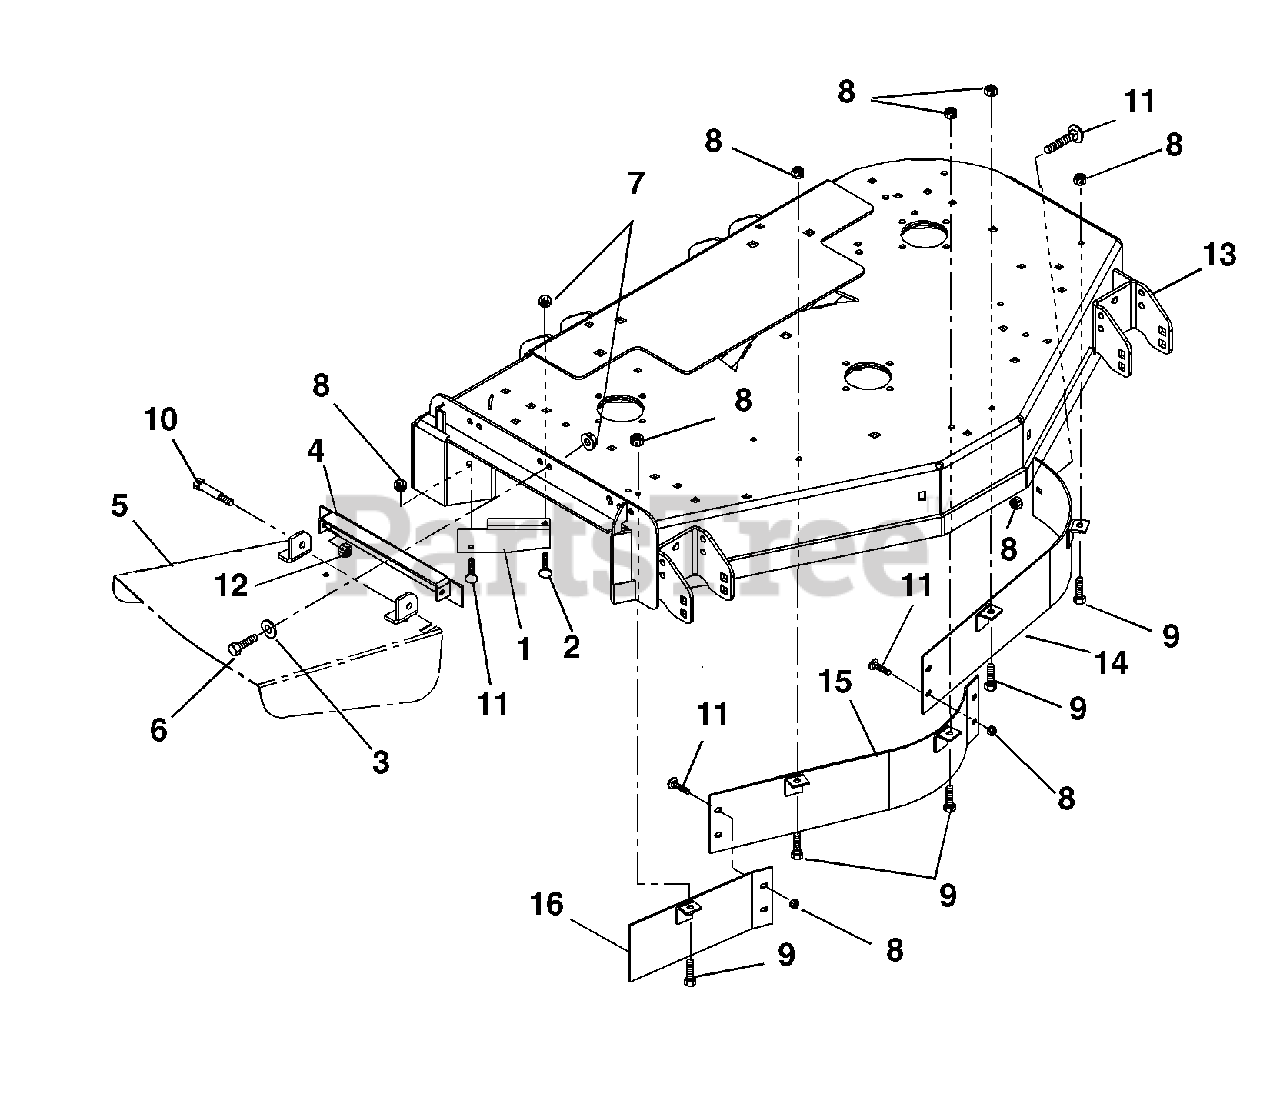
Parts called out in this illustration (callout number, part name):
1	DEFLECTOR - 52"/34"
1	DEFLECTOR, 60" (BLACK)
2	@BLT-RDHDSQNK .38-16X1.00 G5YZ
3	@WSHR-FL-STL.38X.875X.083 YWZC
4	WMT, DISCH CHUTE BRKT - ORANGE
4	WMT, CHUTE BRKT
5	DISCH CHUTE - ORANGE
5	WMT, 60" DISCHARGE CHUTE
6	@BLT-HEX .38-16X1.00 GR5 YWZC
7	@NUT-LK-TOP-FLG .38-16 YWZC
8	@NUT-LK-TOP-FLG .31-18 YWZC
9	@BLT-HEX .31-18X.75 GR5 YWZC
10	BLT-SHLDR .38-16X.38 SKH
11	@BLT-RDHDSQNK .31-18X.75 G5YZ
12	@NUT-LK-CTR .38-16 YWZC
13	WMT, 52" MOWER DECK - ORANGE
13	60" 7 GA. MOWER DECK - ORANGE
14	BAFFLE - LEFT FRONT - 52"
14	BAFFLE - LEFT FRONT - 60"
15	BAFFLE - CENTER FRONT - 52"
15	BAFFLE - CENTER FRONT - 60"
16	BAFFLE - RIGHT FRONT - 52"
16	BAFFLE - RIGHT FRONT - 60"
